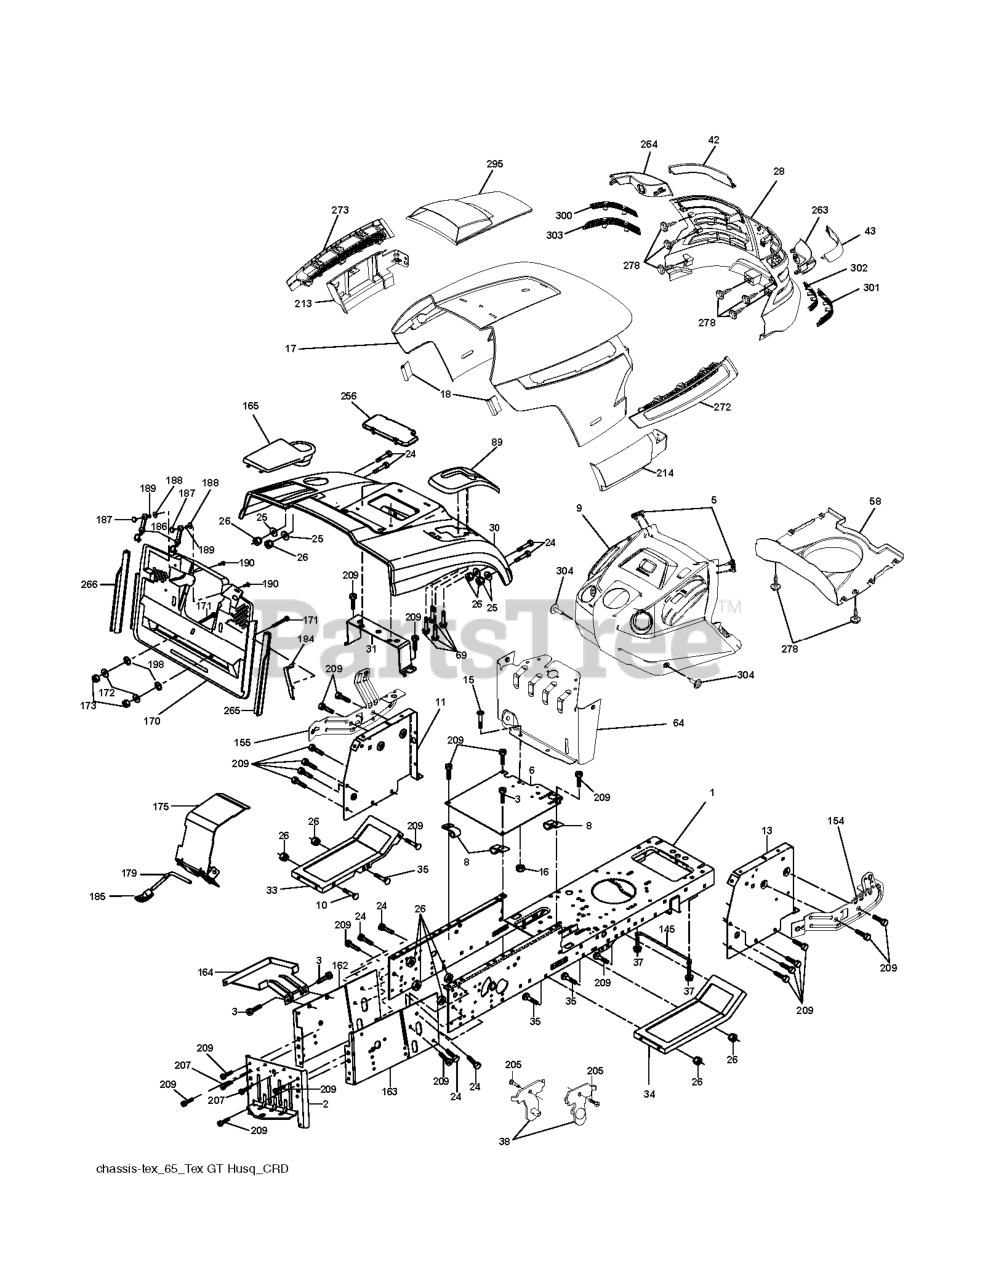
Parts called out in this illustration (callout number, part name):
2	DRAWBAR
3	SCREW 3/8-16X3/4
5	BUMPER DASH
6	PLATE
8	CLIP,INSULATOR
10	BOLT D
11	PANEL DASH LH
13	PANEL DASH RH
15	Screw, Machine, Truss Head 5/16-18 UNC x 3/4
16	NUT
17	HOOD
18	BUMPER.HOOD.TEX.HUSQVARNA
25	WASHER
26	NUT
28	GRILL.ASM.HUSQ.TG/CRD.W/TRIM
30	CONSOLE.CRD.AUTO.GRY
31	BRACKET SUPPORT FENDER
33	FOOTREST PNT LH
34	FOOTREST PNT RH
37	Screw 5/16-18 x 1/2 Hex, Self Tapping 5/16-18 x 1/2
38	BRACKET ASM PIVOT MOWER REAR
42	LENS.LH.TEX.GT.HUSQ.CL
43	LENS.RH.TEX.GT.HUSQ.CL
58	AIR.DUCT.HOOD.TEX.GT.HUSQ
69	SCREW.HI-LO.CONSOLE
89	CONSOLE.CRD.AUTO.GREY.2005
145	ROD.PIVOT.HOOD
162	BRACKET
163	BRACKET EXTEN CHASSIS RH CRD
165	RP.COVER.BATTERY.CRD.GREY
172	WASHER
175	DOOR TRAP
179	ROD PIVOT FBI
184	BRACKET.ACTUATOR.BAGGER.SRD
186	LATCH ASSY
187	WELDNUT
189	LOCKWASHER #10
190	SCREW
207	SCREW, 5/16-18 X 1/2
209	SCREW, 3/8-16X3/4
213	SKIRT.HOOD.SIDE.HUSQ.LH.GREY
214	SKIRT.HOOD.SIDE.HUSQ.RH.GREY
256	COVER FENDER CRD
263	BEZEL.RH.TEX.GT.HUSQ
264	BEZEL.LH.TEX.GT.HUSQ
265	SEALING
266	SEALING
272	VENT.SIDE.HOOD.HUSQ.RH.GREY
273	VENT.SIDE.HOOD.HUSQ.LH.GRAY
278	SCREW
295	VENT.ASM.TORPHD.HUSQGT.LOGO.CL
300	INSERT.HEX.GRILL.HUSQ.
301	INSERT.HEX.GRILL.HUSQ.GREY
302	INSERT.HEX.GRILL.HUSQ.
303	INSERT.HEX.GRILL.HUSQ.
304	SCREW 14-20 X 5/8
